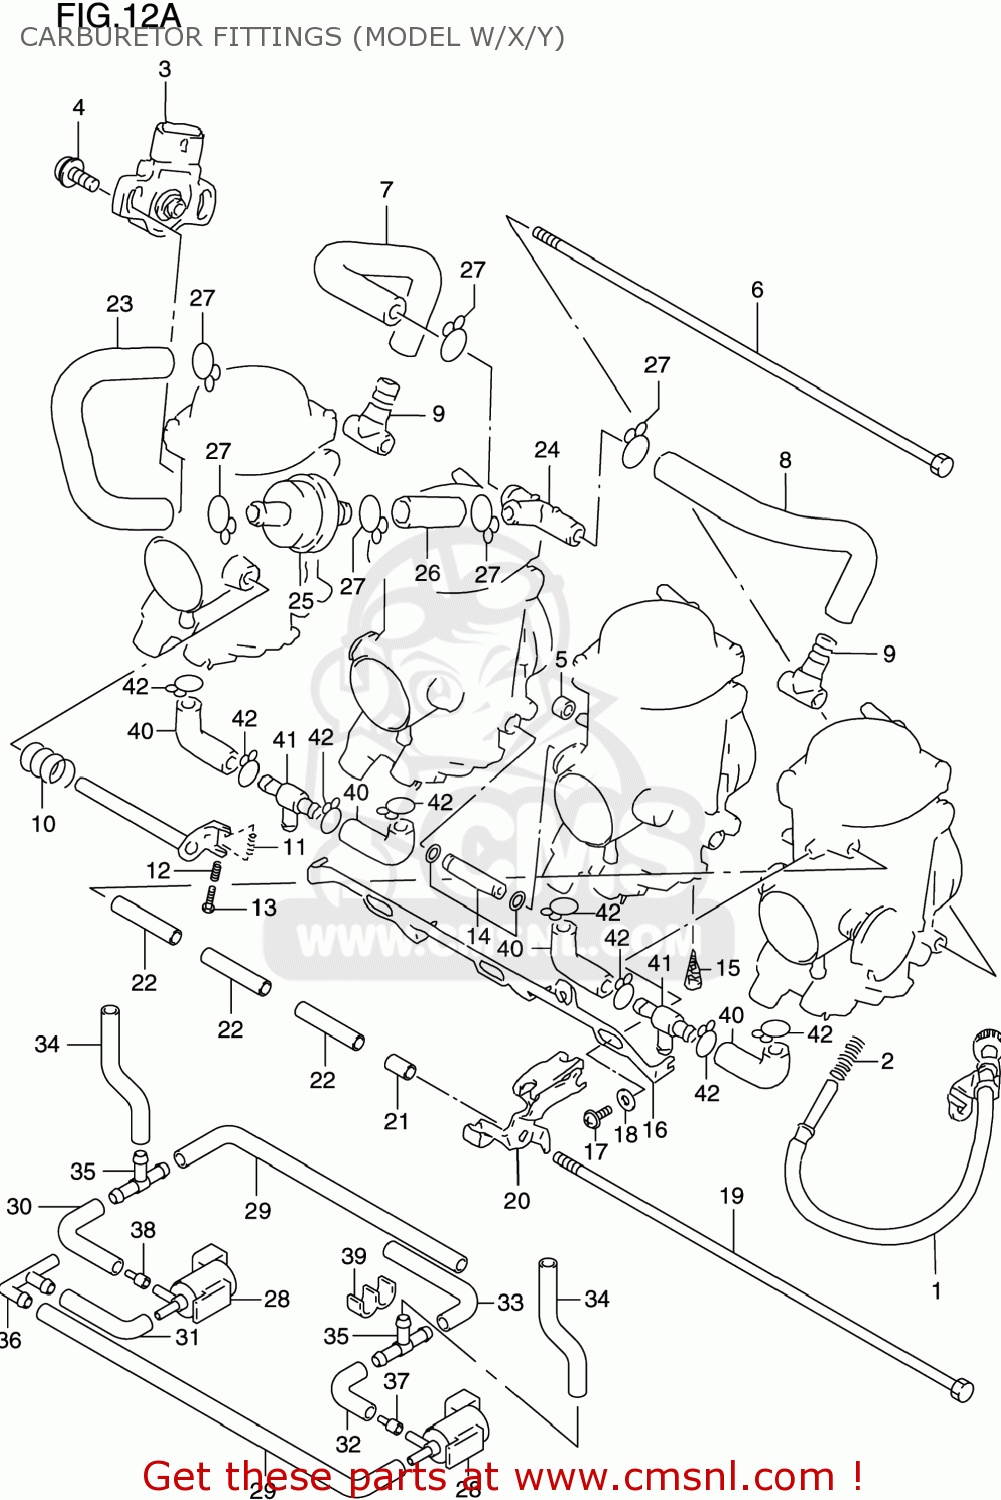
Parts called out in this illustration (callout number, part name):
1	ADJUSTER
2	SPRING
3	SENSOR ASSY,THROTTLE
4	SCREW,SENSOR
5	PIPE
6	BOLT
7	HOSE
8	HOSE
9	3 WAY
10	SPRING
11	SPRING,THROTTLE SCREW
12	SPRING
13	SCREW
14	NIPPLE,CARBURETOR
15	FILTER
16	LEVER,STARTER
17	SCREW
18	PACKING
19	BOLT
20	BRACKET
21	PIPE
22	PIPE
23	HOSE,AIR VENT(NO.1)
24	JOINT
25	FILTER,AIR VENT
26	HOSE(11X15X600)
27	CLIP
28	VALVE,PILOT AIR
29	HOSE(3X7X600)
30	HOSE(3X7X600)
31	HOSE(3X7X600)
32	HOSE
33	HOSE
34	HOSE
35	3 WAY
36	JOINT
37	JET,AIR(100)
38	JET,AIR(100)
39	CLAMP
40	HOSE
41	NIPPLE
42	CLIP
